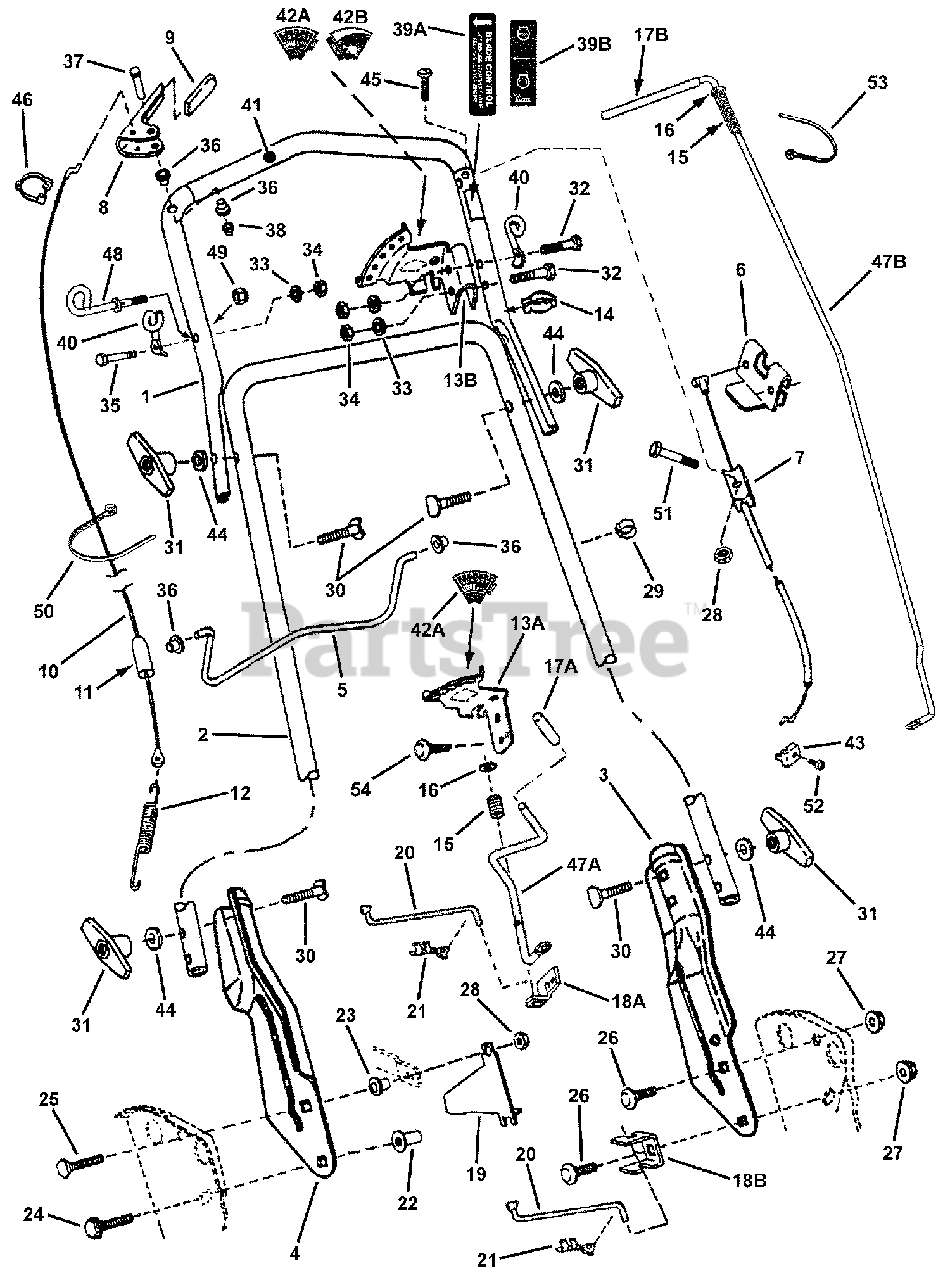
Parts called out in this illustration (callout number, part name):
1	HANDLE, Upper
2	HANDLE, Middle- 1990
3	HANDLE, Lower Left Hand
4	HANDLE, Lower Right Hand
5	BAIL, OPC Control (12.5" Wide)
6	CLIP, Blade Control
7	CABLE, Blade Control (49-1/4" long)
7	CABLE, Blade Control (46.-15/16" long)
8	HANDLE, Wheel Drive
9	GRIP, Wheel Drive Handle
10	CABLE, Clutch Pull (Z-Bend, 38-5/8" long)
11	COVER, Vinyl
12	SPRING, Clutch
13A	SECTOR, Speed
13B	SECTOR, Speed
14	WIRE TIE, 1.29" Long (Black)
15	SPRING, Speed Control
16	WASHER, 3/8" Flat
17A	GRIP, Speed Control Handle
17B	GRIP, Speed Control Handle
18A	BRACKET, Speed Control Rod
18B	ANCHOR, Speed Control
19	GUIDE, Lower V-Belt
20	ROD, Transfer
21	CLIP, Transfer Rod 1/4"
22	TEE-NUT, 5/16-18
23	BUSHING, Differential
24	BOLT, 5/16-18 x 3/4" Hex Flange Lock GR5
25	SCREW, 5/16-24 x 1" Hex Head Cap GR5
26	BOLT, 5/16-18 x 5/8" Short Neck Carriage GR5
27	NUT, 5/16-18 Hex Flange Lock GR5
28	NUT, 5/16-24 Hex Center Lock GR5
29	CLIP, Cable/Wiring
30	SCREW, 5/16-18 x 1-7/8" Curved Head GR2
31	T-KNOB, 5/16-18 (BLACK)
32	SCREW, 1/4-20 x 1-1/2 Hex Head Cap GR5
33	WASHER, 1/4" Internal Tooth Lock
34	NUT, 1/4-20 Hex GR5 or B
35	SCREW, 1/4-20 x 2" Hex Head Cap GR5
36	BUSHING
37	PIN, Clutch Handle
38	PUSH-NUT, 1/4" (for handle pin)
39A	DECAL, Blade Control (Left Hand Side)
39B	DECAL, Blade Control (Left Hand Side)
40	GUIDE, Rope
41	FOAM GRIP, .84 I.D. x 11" long
42A	DECAL, Speed Select
42B	DECAL, Speed Select (Euro)
43	CLAMP, Casing
44	WASHER, 5/16" Internal Tooth Lock
45	SCREW, 5/16-24 x 1-1/2" Round Hd. Machine, GR5
46	CLAMP, 7/8" Double Cable
47A	LEVER, Speed Control
47B	LEVER, Speed Control
48	GUIDE, Rope
49	NUT, 1/4-20 Hex GR5 or B
50	CABLE-TIE, 7"
51	SCREW, 1/4-20 x 1-1/2" Hex Head Cap, GR5
52	SCREW, #10-32 x 5/8" Hex Head Self-Tap
53	WIRE TIE, 11" Long (Black)
54	BOLT, 5/16-18 x 1" Square Neck Carriage GR5
